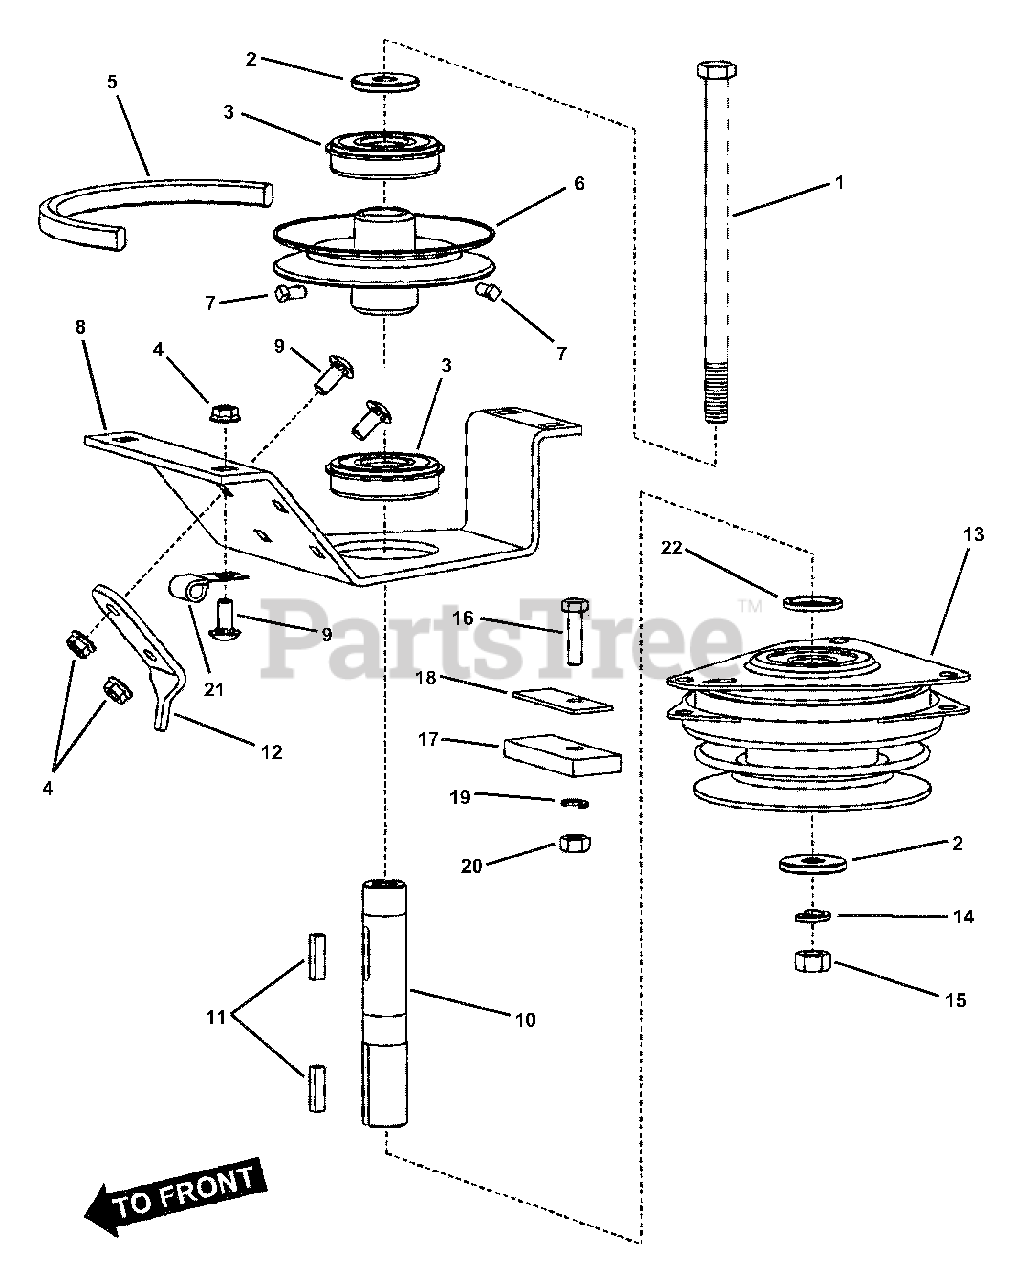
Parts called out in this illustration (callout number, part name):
1	SCREW, 7/16-20 x 8" Hex Head Cap, Grade 5
2	WASHER, 7/16 x 1" O.D. Flat
3	BEARING, 6305 w/Snap-Ring
4	NUT, 5/16-18, Grade 5
5	V-BELT, Drive 5L Cogged, 50.170" nominal effective length
6	PULLEY, Jackshaft
7	SCREW, 1/4-20 x 1/2" Set w/Patch
8	SUPPORT, Jackshaft
9	BOLT, 5/16-18 x 3/4 Carriage, Grade 5
10	JACKSHAFT
11	KEY, 1/4 x 1" Square
12	BRACKET, Anti-Rotate (Ogura) (33" units)
13	CLUTCH, Electric (Ogura) (33" units)
14	WASHER, 7/16" Split Lock
15	NUT, 7/16-20, Grade B
16	SCREW, 5/16-18 x 1-1/4", Hex Head Cap, Grade 5
17	BUMPER, Electric Clutch
18	WASHER, Rectangular Steel
19	WASHER, 5/16" Split Lock
20	NUT, 5/16-18, Grade 5
21	CLIP, Wire, 7/16
22	WASHER
